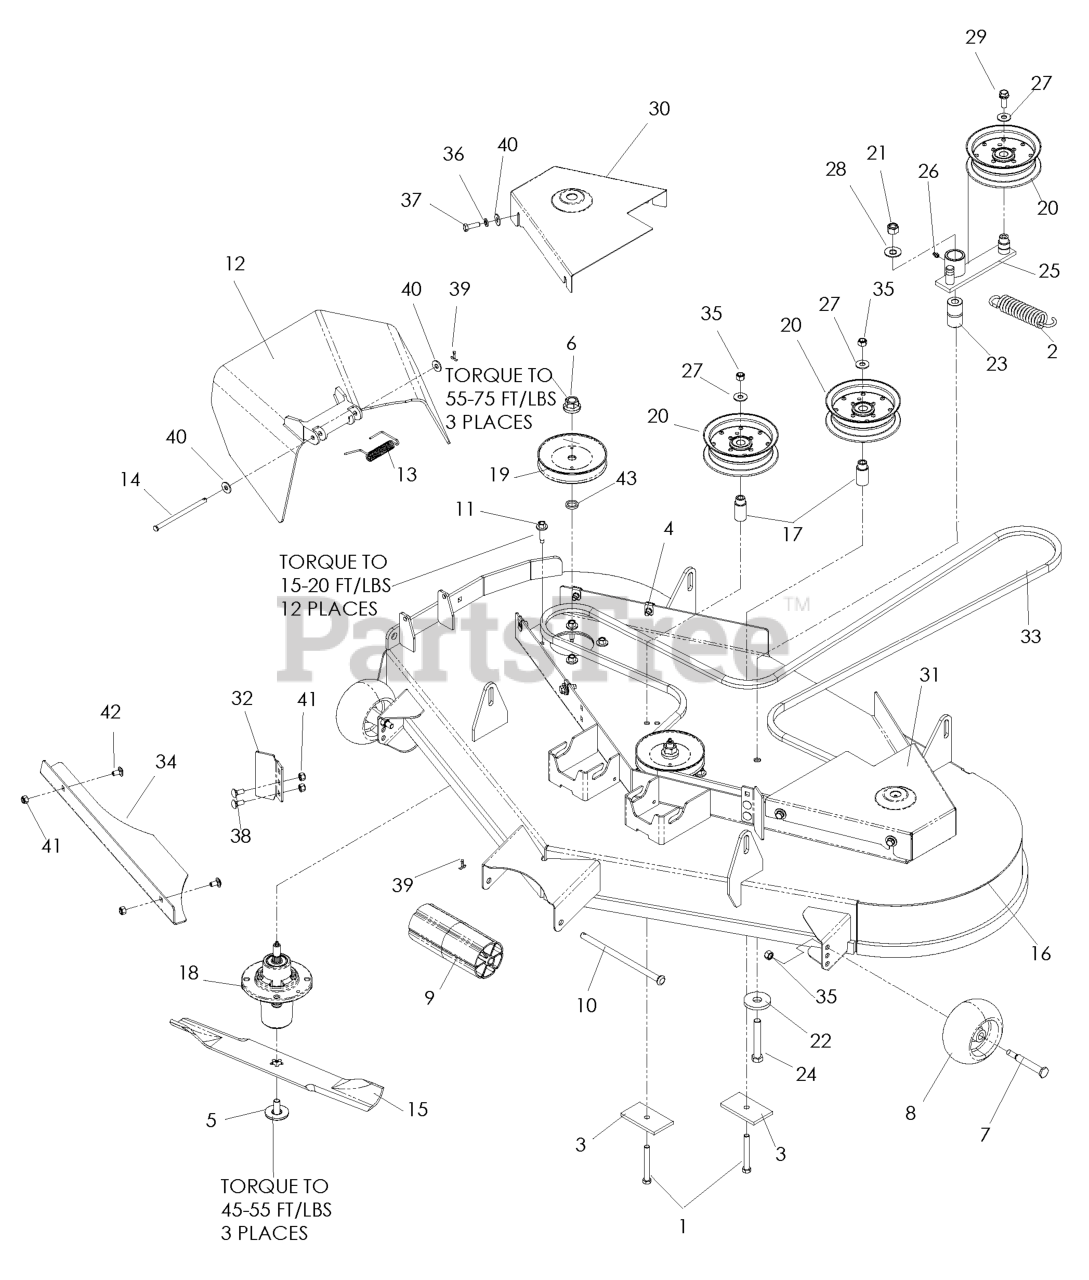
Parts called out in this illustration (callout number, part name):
1	HCS 3/8C X 3
3	SUPPORT PLATE
4	U-CLIP 5/16-18 NUT RETAINER
5	BLADE BOLT ASSY-7/16" TB REPL
6	LOCKNUT - 9/16
7	SHOULDER BOLT 1/2X2-5/8 ZD SPE
8	GAUGE WHEEL
9	NOSE ROLLER 48"
10	NOSE ROLLER ROD
11	WASHER HEAD SCREW
12	DISCHARGE CHUTE 52"
13	SPRING - TORSION
14	PIN-CLEVIS 5/16 DIA X 5.19 ZD
15	BLADE, 18"
16	DECK W/DECALS 52"
17	IDLER BUSHING
18	MANDREL.DECK.ASSEMBLY
19	PULLEY
20	PULLEY, IDLER
21	NUT 1/2-13 HEX NYLOC ZD
22	WASHER, SUPPORT
23	PIVOT BUSHING
24	HCS 1/2C X 3 1/4
26	ZERK
27	WASHER 3/8 FLAT
28	WASHER 1/2 FLAT
29	4CS 3/8C X 1 SERRATED HEAD
30	BELT SHIELD, RIGHT 52, ORG
31	BELT SHIELD, LEFT 52, ORG
33	BELT, DECK 52"
34	CONFINEMENT PLATE, 52"
35	NUT 3/8-16 NYLOC
36	WASHER.LOCK.HVY.HLCL.SPR.5/16
37	HCS 5/16C X 1
38	BOLT 5/16C X 3/4" CARRIAGE
39	RP_COTTER PIN 1/8 X 3/4
40	WASHER 5/16 FLAT
41	NUT 5/16 NYLOC
42	CARRIAGE BOLT 5/16C X 5/8"
43	WASHER-SPACER
